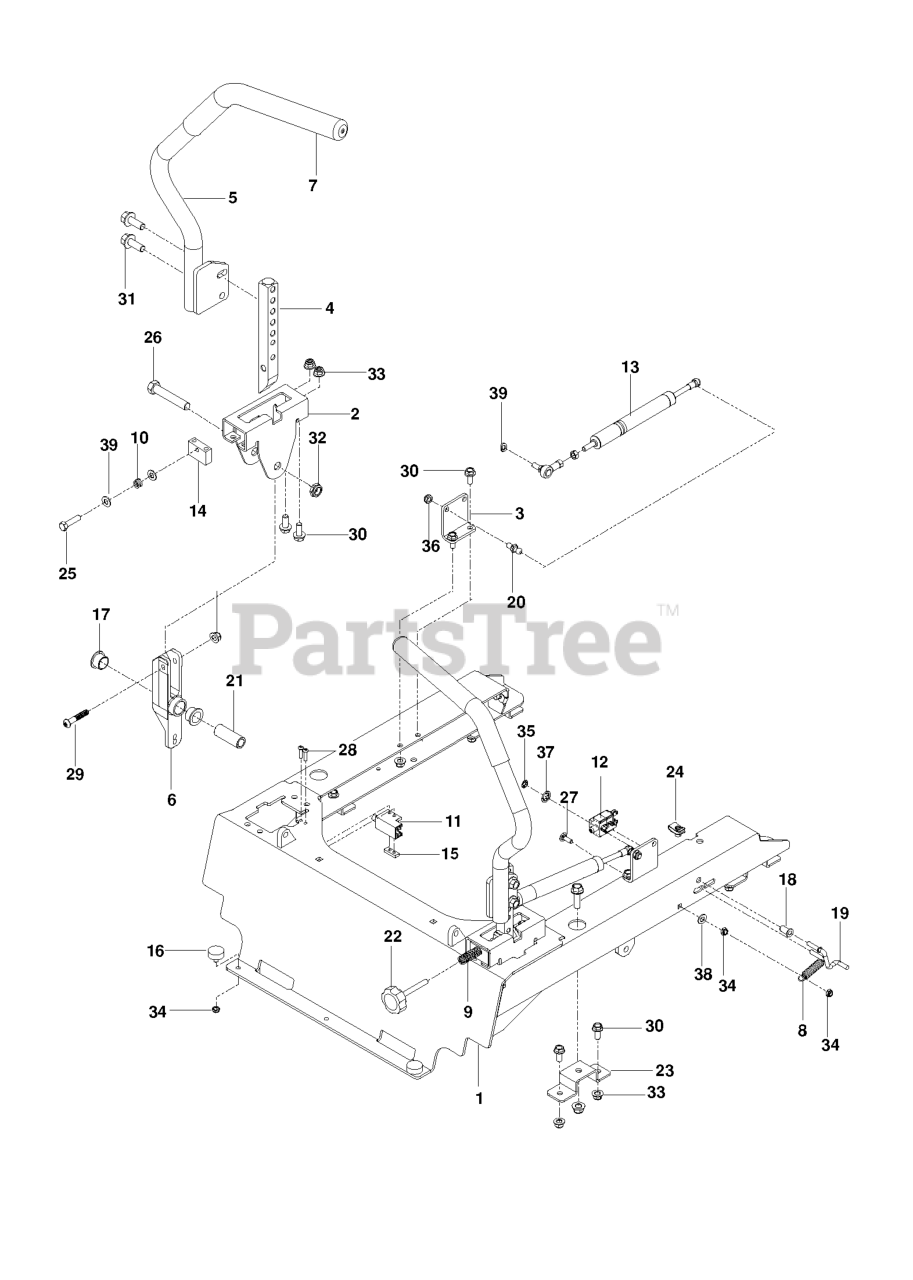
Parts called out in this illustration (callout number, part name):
1	FRAME SEAT MOUNT ORANGE
2	BRACKET, CONTROL
3	BRACKET.DAMPNER
4	LEVER, MOTION
5	LEVER.WITH GRIP.RT
6	LEVER.CONTROL.SHORT
7	GRIP - DRIVE LEVER 12"
8	SPRING, EXTENSION
9	SPRING COMPRESSION 2.0
11	SWITCH, INTERLOCK
12	SWITCH, BRAKE 3P
13	ASSEMBLY, DAMPENER
14	BLOCK.TRACKING
15	TAPPED PLATE
16	BUMPER, 1/4-20 STUD, 1/4
17	BEARING, FLANGE
18	BUSHING, 1/4 FLANGE
19	LINK, SWITCH
20	STUD.BALL.10MM
21	SPACER, PIVOT CONTROL
23	MOUNT, MID-SECTION, BLK
24	U-CLIP 5/16-18 NUT RETAINER
25	BOLT, TAP 5/16-18
26	HCS 1/2C X 2 3/4
27	RHSNB 1/4C X 3/4
28	SCR #10-24 X .75 SKT HD BLK
29	SCREW 5/16-18 X 1 3/4 BTN-HD
30	HHFS 5/16-18 X 3/4
31	HHFS 3/8-16 X 1 GRD 5 ZD
32	NUT 1/2-13 HEX JM NYL
33	5/16-18 NYLOC FLANGE NUT
34	JAM NUT 1/4C (2 2 PW01)
36	NUT 5/16 NYLOC
37	NUT 3/8 PALNUT RTNG BLK PHOS
38	FLAT WASHER 5/16 SAE
39	WASHER.LOCK.HVY.HLCL.SPR.5/16
